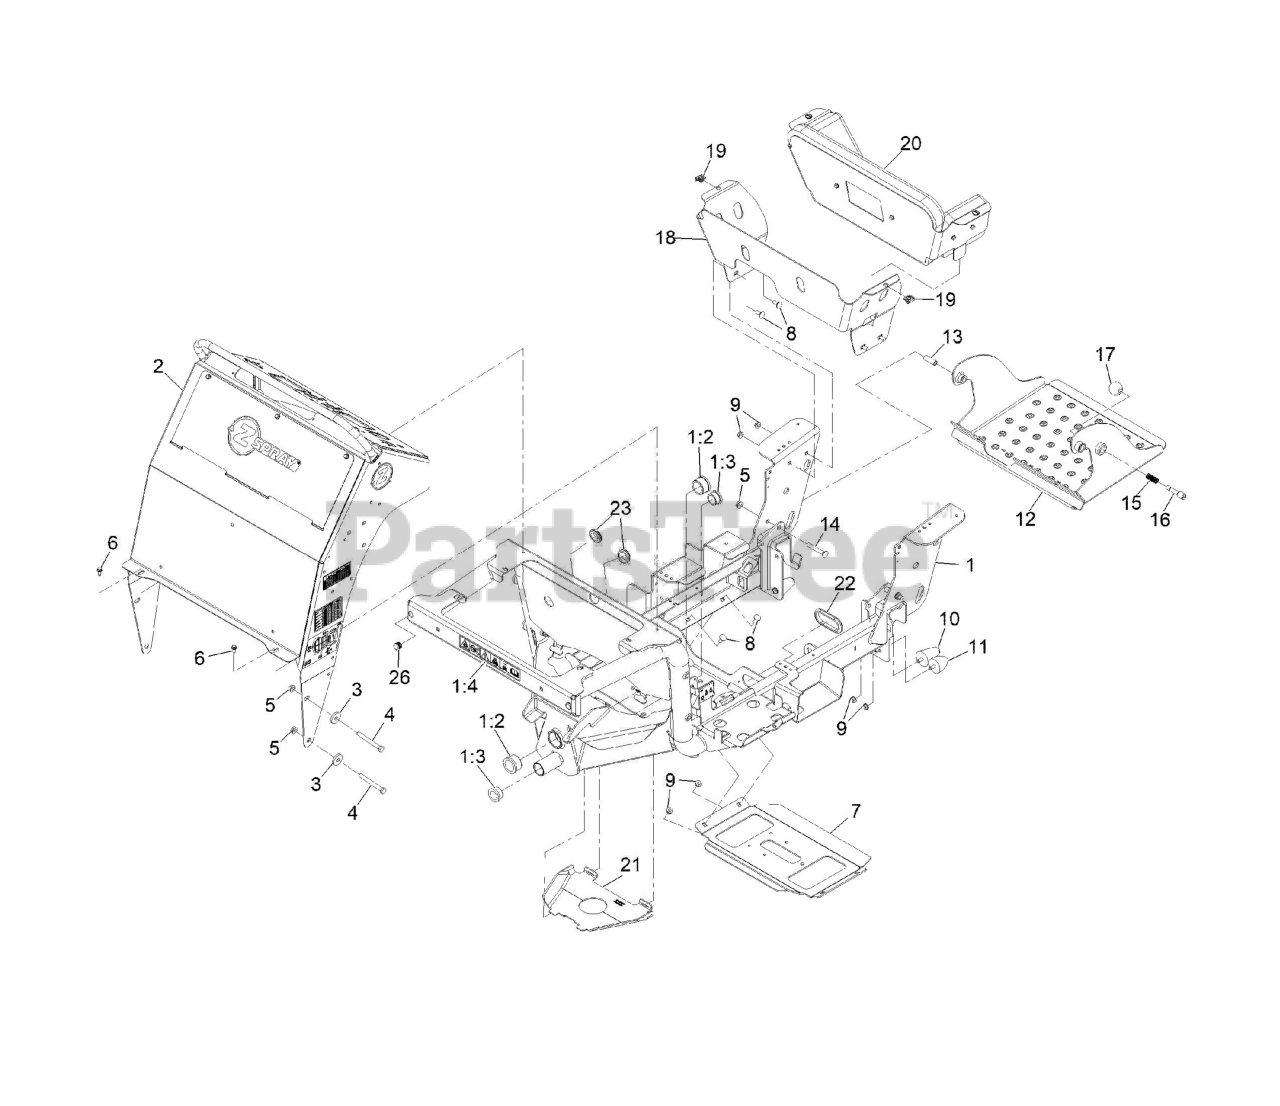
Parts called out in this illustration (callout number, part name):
1	Frame ASM
1:2	BEARING-FLANGED
1:3	BEARING-FLANGED
1:4	DECAL-DOWN, TIE
2	Control Tower ASM
4	SCREW-HH
6	SCREW-HWH
7	GUARD-LOWER
8	SCREW-CARR
10	BUMPER-RUBBER
11	BUMPER-RUBBER
12	OPERATOR PLATFORM ASM
13	BUSHING-PIVOT, PLATFORM
14	SCREW-CARR
16	PIN-LATCH
17	KNOB-BALL
18	MOUNT-PAD, KNEE
19	RECEPTACLE-CLIP, MINI
20	ASM-Pad
21	SHIELD-DUST
22	GROMMET
23	GROMMET
26	PLUG-TUBE
